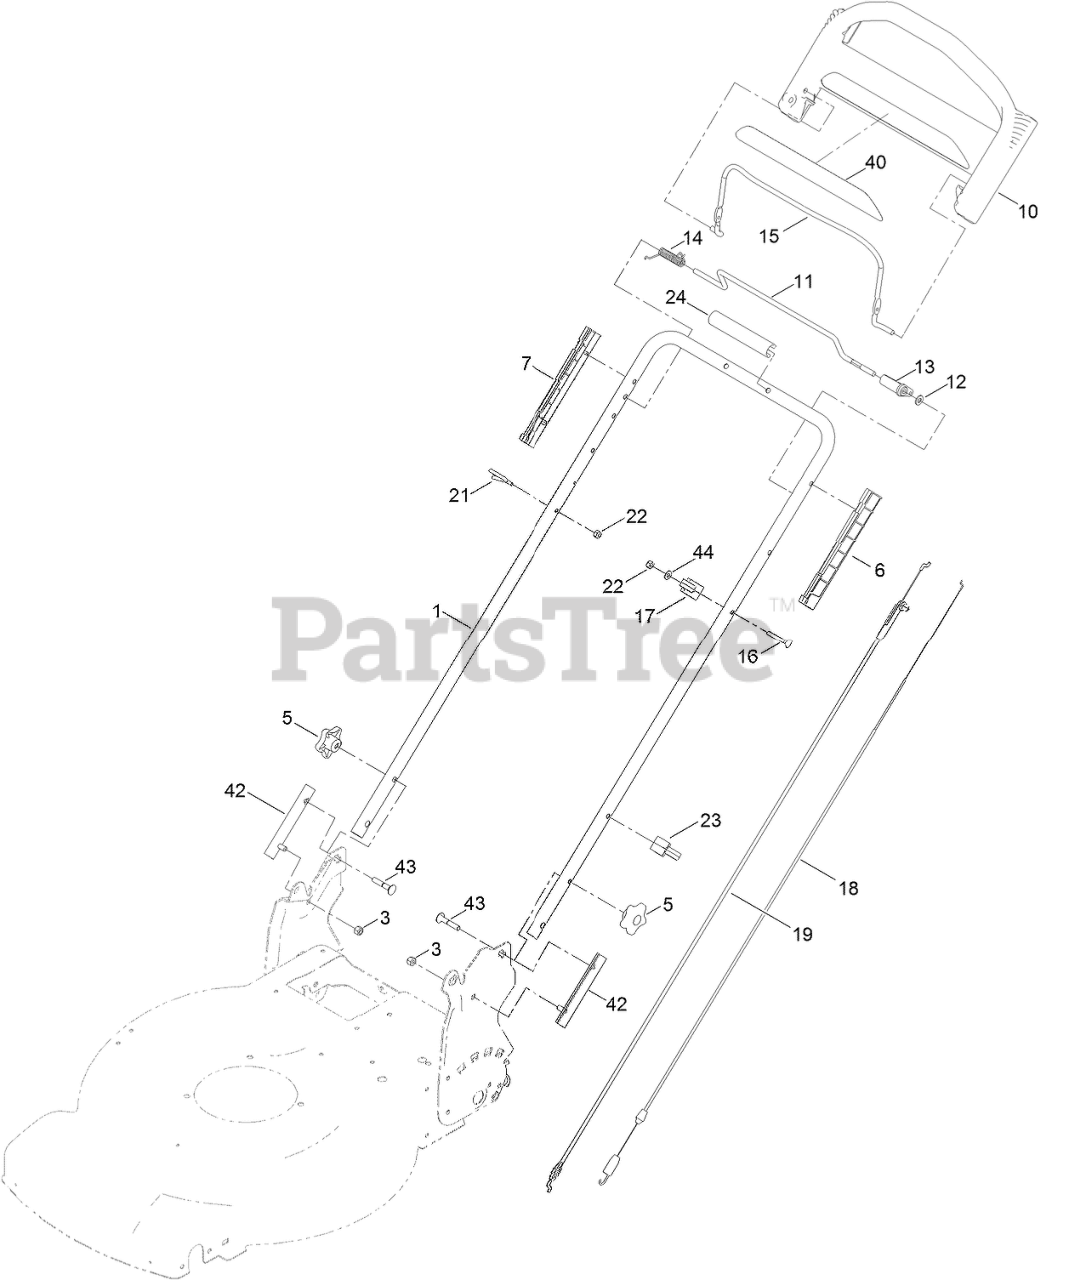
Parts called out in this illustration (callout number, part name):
3	NUT-LOCK, NI
5	KNOB-HANDLE
6	GUIDE-LH
7	GUIDE-RH
10	HANDLE-CONTROL
11	BAR-CONTROL, TRACTION
12	WASHER-PLAIN
13	LEVER-TRACTION
14	SPRING-TORSION
15	BAIL-BRAKE
16	SCREW
17	ANCHOR-CABLE
18	CABLE-TRACTION
19	CABLE-BRAKE
21	GUIDE-ROPE
22	NUT-LOCK, NI
23	GUIDE-CABLE
24	HANDLE-COVER
42	SADDLE-HANDLE
43	SCREW-CARR
44	WASHER-FLAT
